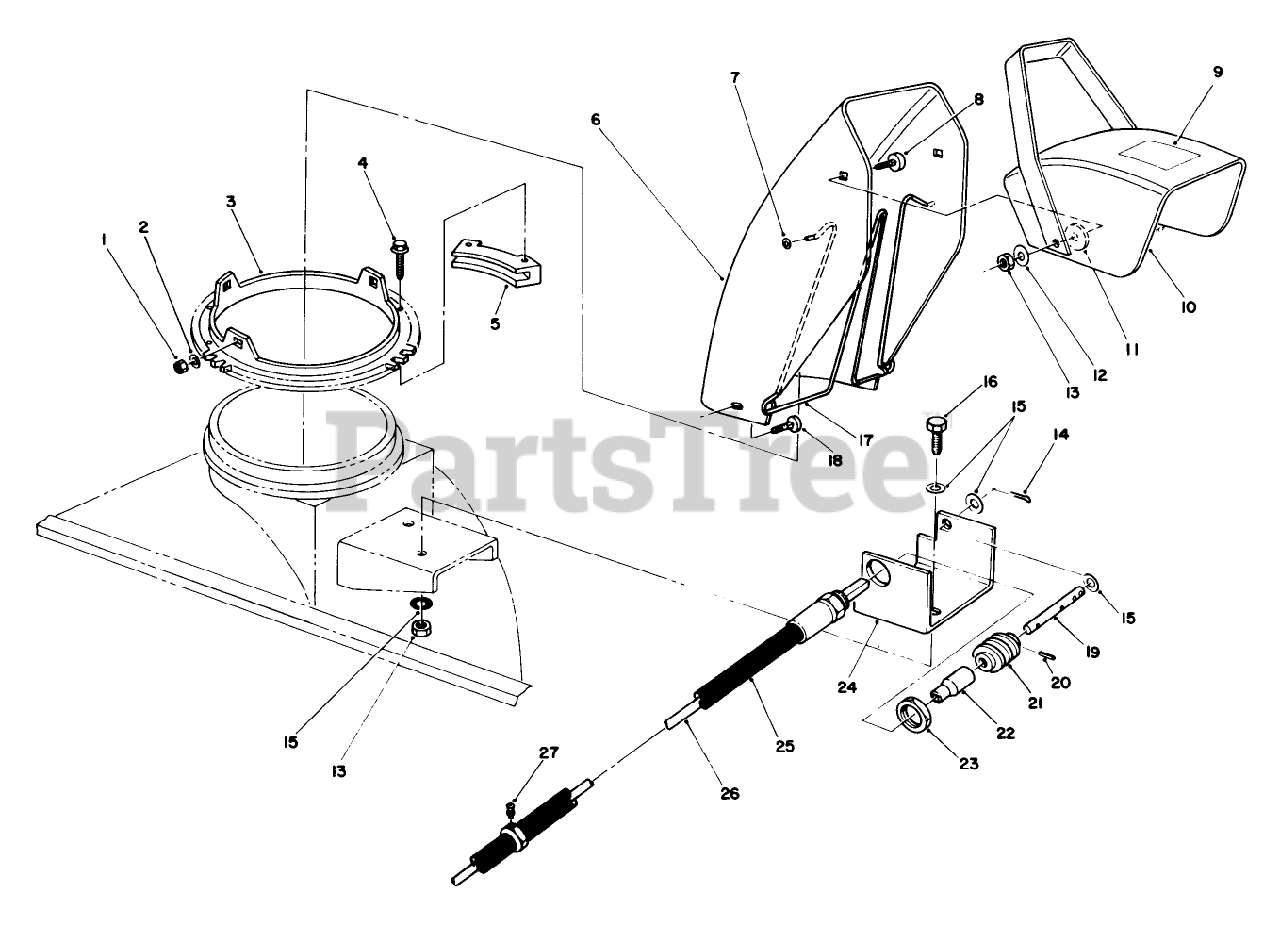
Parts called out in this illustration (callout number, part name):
1	NUT-LOCK, NI
2	WASHER-PLAIN
3	Screw
4	SCREW-SPECIAL
5	RETAINER-CHUTE
6	Chute-Upper
7	NUT-PUSH
8	SCREW-CARR
9	Decal-Discharge
10	Deflector
11	WASHER-RUBBER
12	WASHER-BELLEVILLE
13	NUT-LOCK, NI
14	PIN-COTTER
15	WASHER-FLAT
16	SCREW-HH
17	CHUTE WIRE
18	SCREW-CARR
19	SHAFT-GEAR, WORM
20	PIN-SPRING
21	GEAR-WORM, CHUTE
22	COUPLER
23	LOCKNUT
24	WORM GEAR BRKT R
25	HOSE ASM
26	FLEX SHAFT
27	FITTING-GREASE
